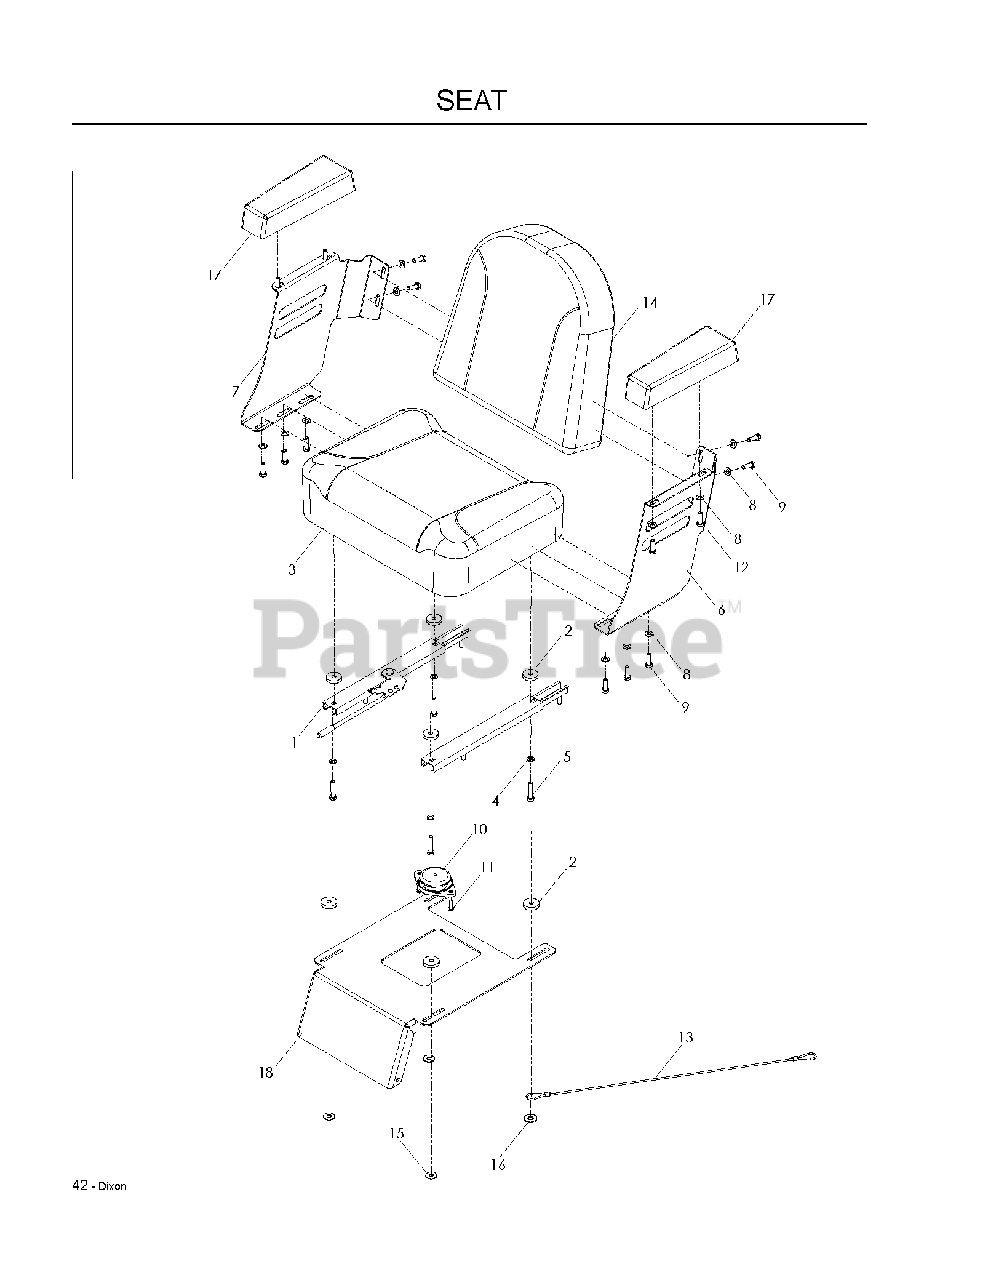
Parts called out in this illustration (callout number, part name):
1	SEAT SLIDE (SET)
2	WASHER NYLON
3	SEAT BOTTOM
4	WASHER 5/16 LOCK
5	5/16-18X1-1/2 HHB GR5WNY
8	FLAT WASHER 5/16 SAE
9	5/16-18X1 HHB G5W/NY
10	SEAT SWITCH MILSCO
11	SCR 1/4-20X3/4 SLTD RDHD GR2ZD
12	HCS 5/16C X 1
13	SEAT LANYARD
14	SEAT BACK
15	WASHER 5/16 FLAT
16	WASHER 3/8 FLAT
18	PAN, SEAT, BLUE
